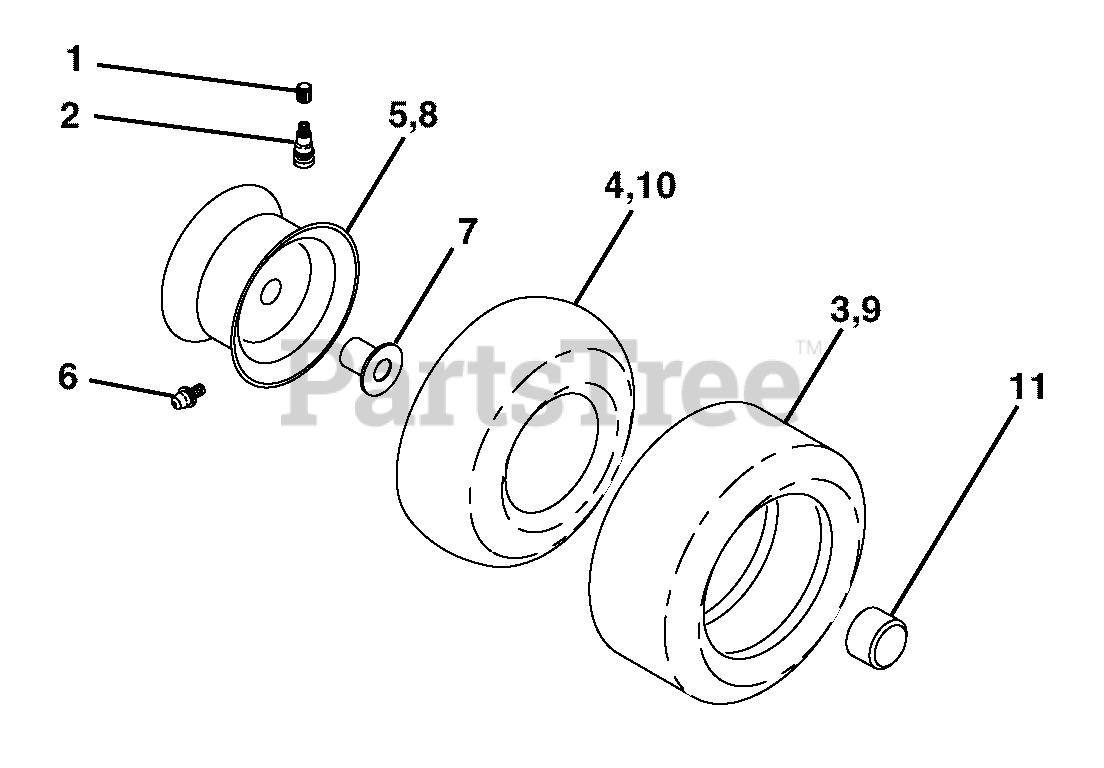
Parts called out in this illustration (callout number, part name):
1	Cap Valve Tire
2	Stem Valve
3	Tire F Ts 15 X 6 0 - 6 Service
4	Tube Front (Service Item Only)
5	Rim Asm 6"front White Service
6	Fitting Grease (Front Wheel Only)
7	Bearing Flange (Front Wheel Only)
8	Rim Asm 8"rear White Service
9	Tire R Ts 18x9.5-8 C Service
10	Tube Rear (Service Item Only)
11	Cap Axle Blk 1 50 X 1 00
